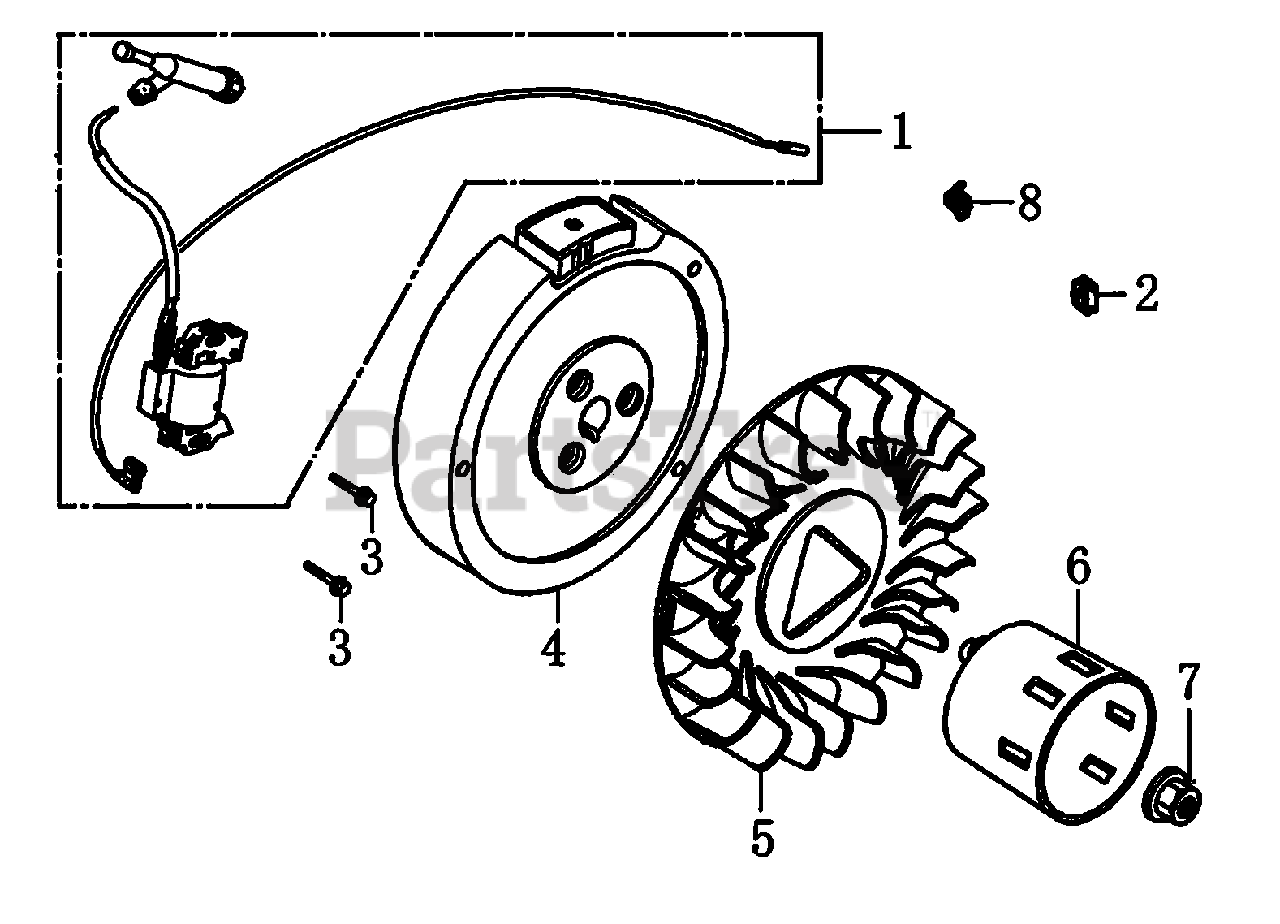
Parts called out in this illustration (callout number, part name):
1	COIL ASSY, IGNITION
2	GROMMET, CORD
3	BOLT, FLANGE M6X25
5	FAN, COOLING
6	PULLEY, STARTER
7	NUT, 16MM
8	HOLDER, STOP SWITCH
